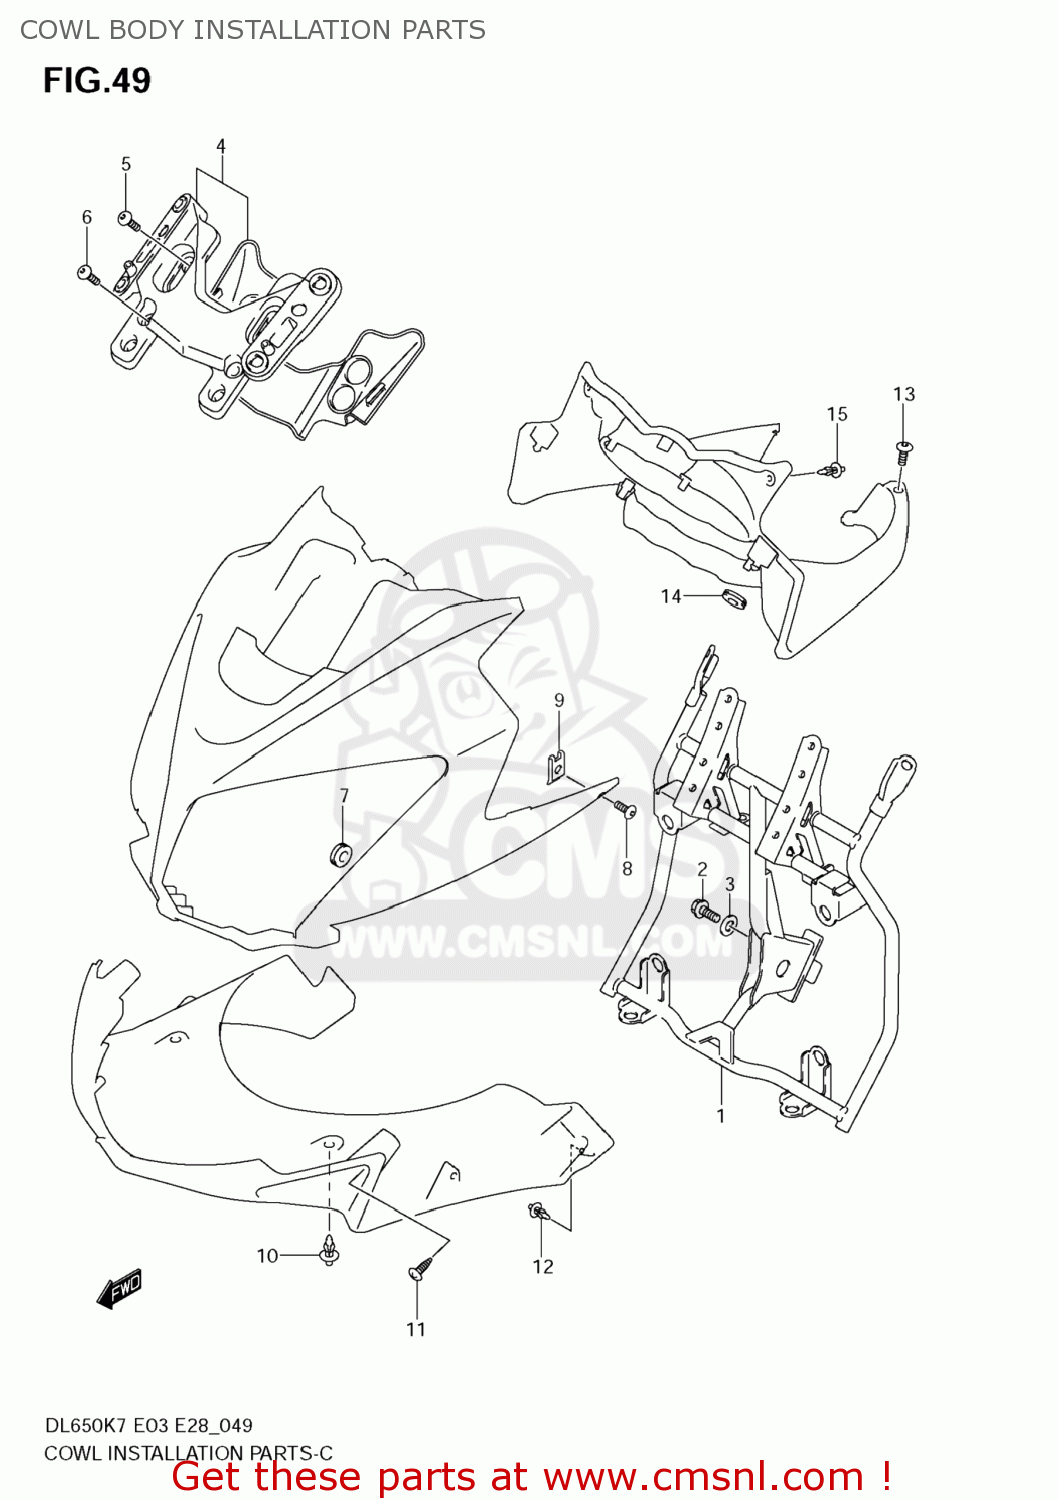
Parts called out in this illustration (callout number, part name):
1	BRACE,COWLING
2	BOLT
3	WASHER
4	BRACE ASSY,WINDSCREEN
5	SCREW(6X20)
6	SCREW(6X16)
7	CUSHION
8	SCREW(5X13)
9	NUT
10	CLIP
11	SCREW
12	CLIP(BLACK)
13	SCREW(6X10)
14	CUSHION
15	CLIP(BLACK)
